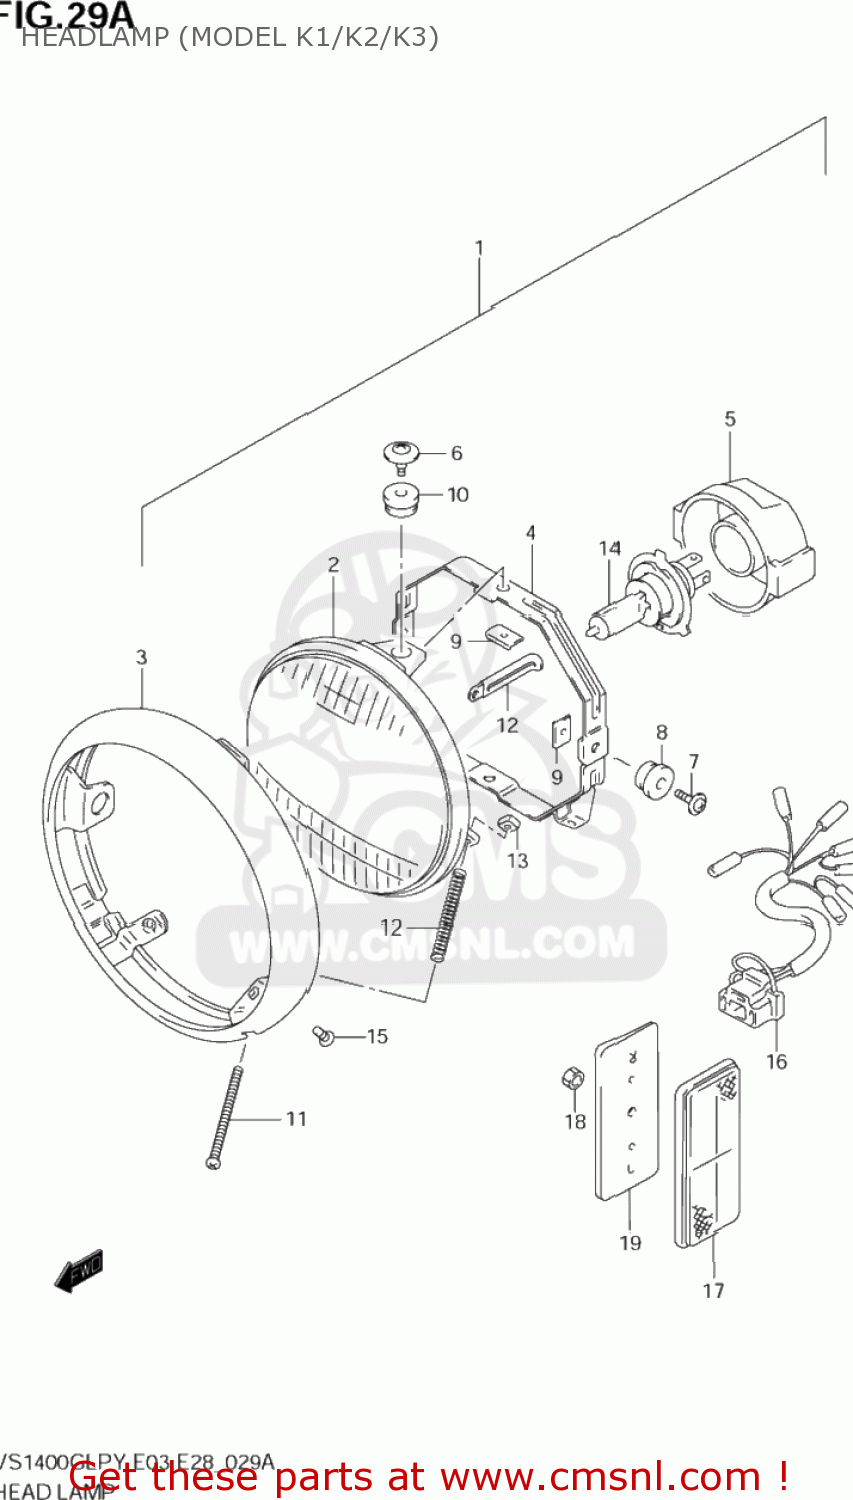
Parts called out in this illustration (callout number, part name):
1	HEADLAMP ASSY
2	UNIT,LAMP
3	RIM
4	RING,MOUNTING
5	COVER
6	SCREW
7	SCREW,MOUNTING
8	CUSHION
9	NUT
10	CUSHION
11	SCREW,ADJUSTING(4X50)
12	SPRING
13	NUT,HEADLAMP ADJUST
14	BULB(12V60/55W,H4)
15	SCREW(5X12)
16	WIRE,HEADLAMP LEAD
17	REFLEX REFLECTOR,FR SIDE
18	NUT
19	SPACER,FR SIDE RR
